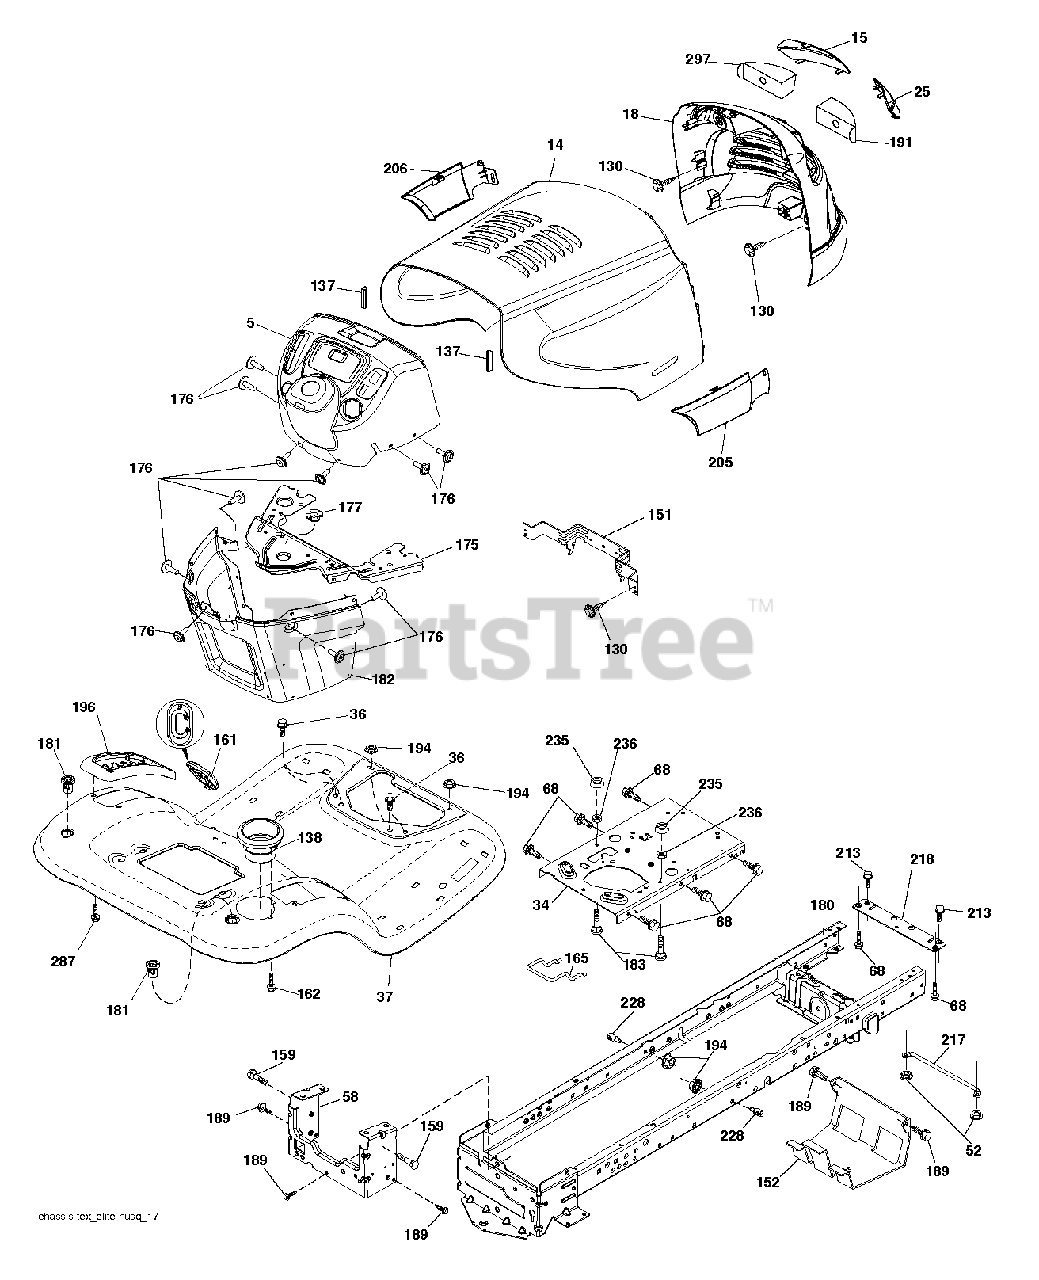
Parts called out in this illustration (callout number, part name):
5	DASH UPPER
14	HOOD.ELT.HUS/BSC.S/TP.SKT.421
18	GRILLE.ELITE HUSQ.BLACK.DL.
34	PLATE.ENGINE.WELDED.CHASSIS
36	SCREW 5/16"
52	LOCKNUT
58	DRAWBAR UPPER 2PC SMALL FENDER
68	SCREW LT
130	SCREW.#10 X 0.750.BOS (2 2)
137	BUMPER.HOOD.LARGE.1.75"
138	CUPHOLDER.TL.TEX.BLACK
151	BRACKET PIVOT
152	SHIELD.BROWNING.W/TEX
159	SCREW, 3/8-16X3/4
161	WINDOW.FUEL.LT.TEX.BLACK
162	SCREW.HI-LO.CONSOLE
165	SUPPORT.TANK.REAR.W/TEX
175	CROSSMEMBER.LT
176	SCREW.#10-24X5/8.RN.QU
177	BUSHING,STEERING
180	CHASS.WLDMNT.TL.12GA/2P.48/54
181	FEND/FTRST.PCH.CPH.NFW
182	DASH.LOWER.LT.CCS
183	BOLT.5/16-18X1-1/4 FULL THD
189	SCREW
191	INSERT LENS
194	NUT LOCK HEX FLANGE 5/16-18
213	BOLT
217	ROD.PIVOT.HOOD
218	X-PIECE.HOOD.STOP.NON/
228	STUD.FASTNER.W/ANTI-ROTATE
235	SPACER FENDER
236	NUT.CENTERLOCK.5/16-
287	SCREW 1/4X20
297	INSERT.REFLECTIVE.RH.
